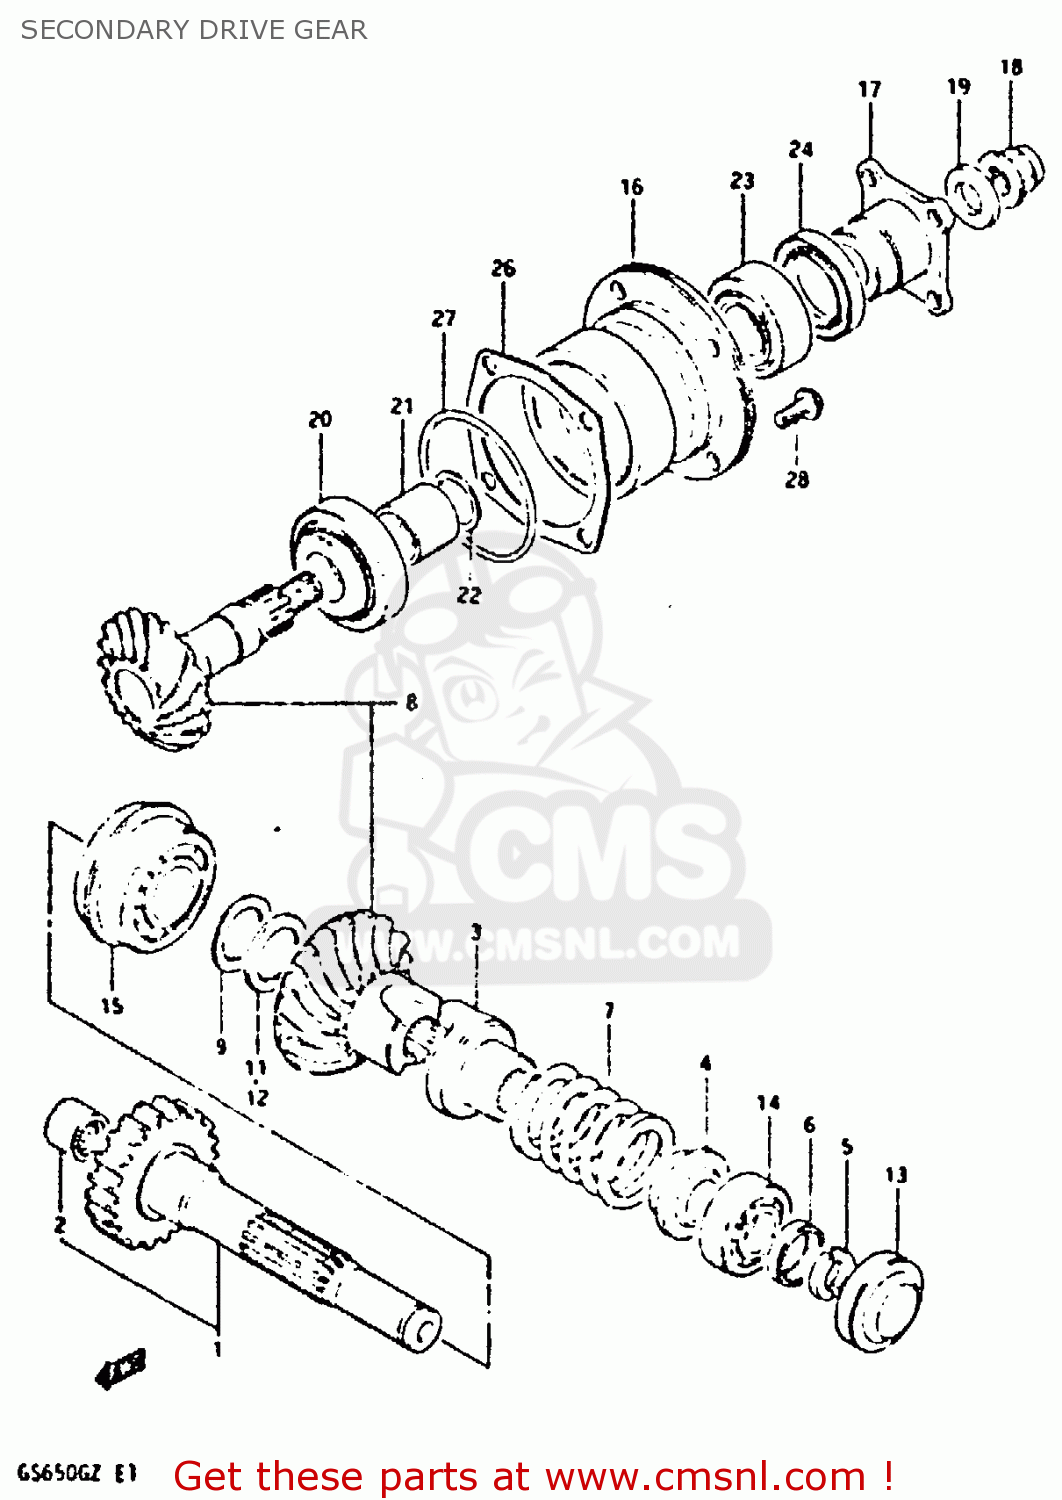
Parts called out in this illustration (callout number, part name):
1	SHAFT,OUTPUT
2	BEARING
3	DOG
4	STOPPER
5	STOPPER,CAM DOG
6	HOLDER,CAM DOG STOPPER
7	SPRING
8	SECONDARY GEAR SET
9	SHIM, RH (T:1.5)
11	SHIM,SECONDARY DRIVE BEVEL
12	SHIM,SECONDARY DRIVE BEVEL
13	PLUG
14	BEARING(20X47X14)
15	BALL BEARING 30X62X24
16	HOUSING,SECONDARY DRIVE
17	FLANGE,UNIVERSAL JOINT
18	NUT
19	WASHER(14X29X4)
20	TAPER,ROLLER BEARING
21	SPACER (25.2X30X40)
22	SHIM (25X30X2
23	BEARING
24	SEAL,OIL(35X52X9)
26	SHIM,DRIVEN GEAR HOUSING
27	O RING(D:3.1,ID:69.4)
28	BOLT
